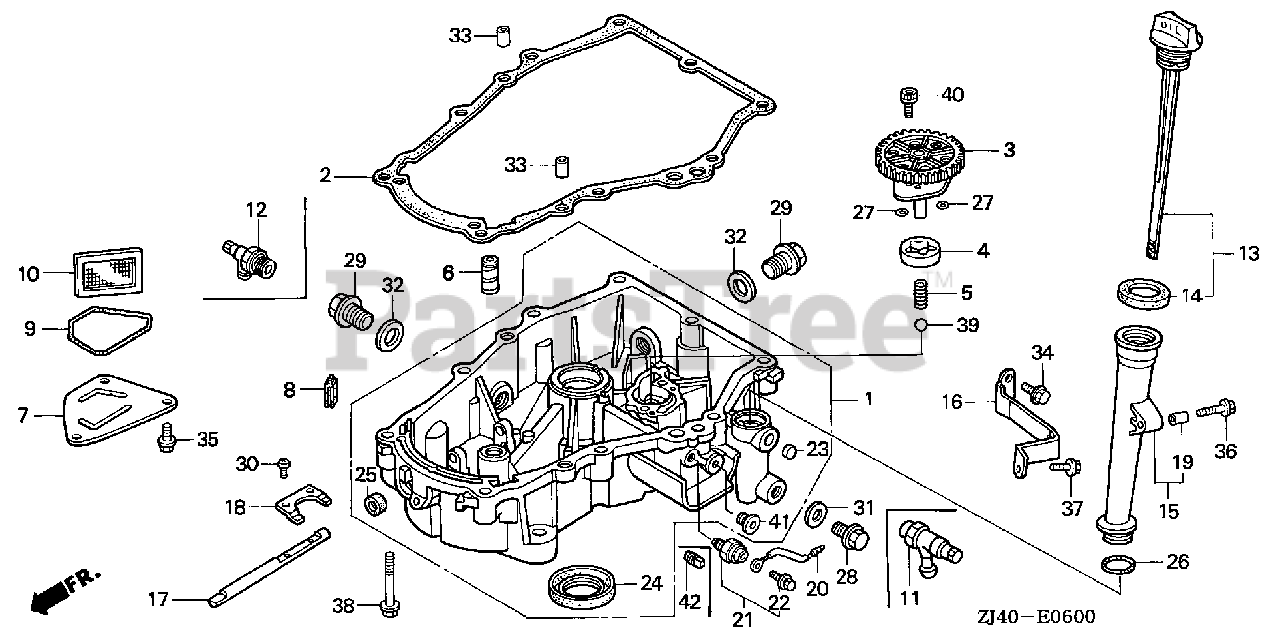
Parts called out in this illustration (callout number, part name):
1	PAN ASSY., OIL
2	GASKET, CASE COVER
3	COVER ASSY., OIL PUMP (TWO BOLTS)
3	COVER ASSY., OIL PUMP (THREE BOLTS)
4	ROTOR, OIL PUMP (OUTER)
5	SPRING, RELIEF VALVE
6	SHAFT, OIL CONTROL
7	PLATE, OIL FILTER
8	RUBBER, OIL RETURN
9	O-RING, OIL PLATE
10	SCREEN, OIL FILTER
11	VALVE, DRAIN (14X1.5)
12	VALVE, OIL SHUT-OFF
13	CAP ASSY., OIL FILLER
14	GASKET, OIL FILLER CAP
15	EXTENSION, OIL FILLER
16	STAY, OIL FILLER EXTENSION
17	SHAFT, GOVERNOR ARM
18	FORK, GOVERNOR
19	COLLAR, EXTENSION
20	WIRE, OIL PRESSURE SWITCH
21	SWITCH, OIL PRESSURE
22	SCREW-WASHER (4X8)
23	PLUG, SEALING (10MM)
24	OIL SEAL (38X58X11)
25	OIL SEAL (10X20X5) (ARAI)
26	O-RING (22.1X2.2)
27	O-RING (13X3.0)
28	BOLT, DRAIN PLUG (14MM)
29	BOLT, DRAIN PLUG (20MM)
30	SCREW, PAN (5X10)
31	WASHER, DRAIN PLUG (14MM)
32	WASHER, DRAIN PLUG (20MM)
33	PIN, DOWEL (8X14)
34	BOLT, FLANGE (6X12)
35	BOLT, FLANGE (6X14)
36	BOLT, FLANGE (6X28)
37	BOLT, FLANGE (8X16)
38	BOLT, FLANGE (8X50)
39	BALL, STEEL (#12) (3/8)
40	BOLT, SOCKET (6X16)
41	BOLT, SEALING (12MM)
